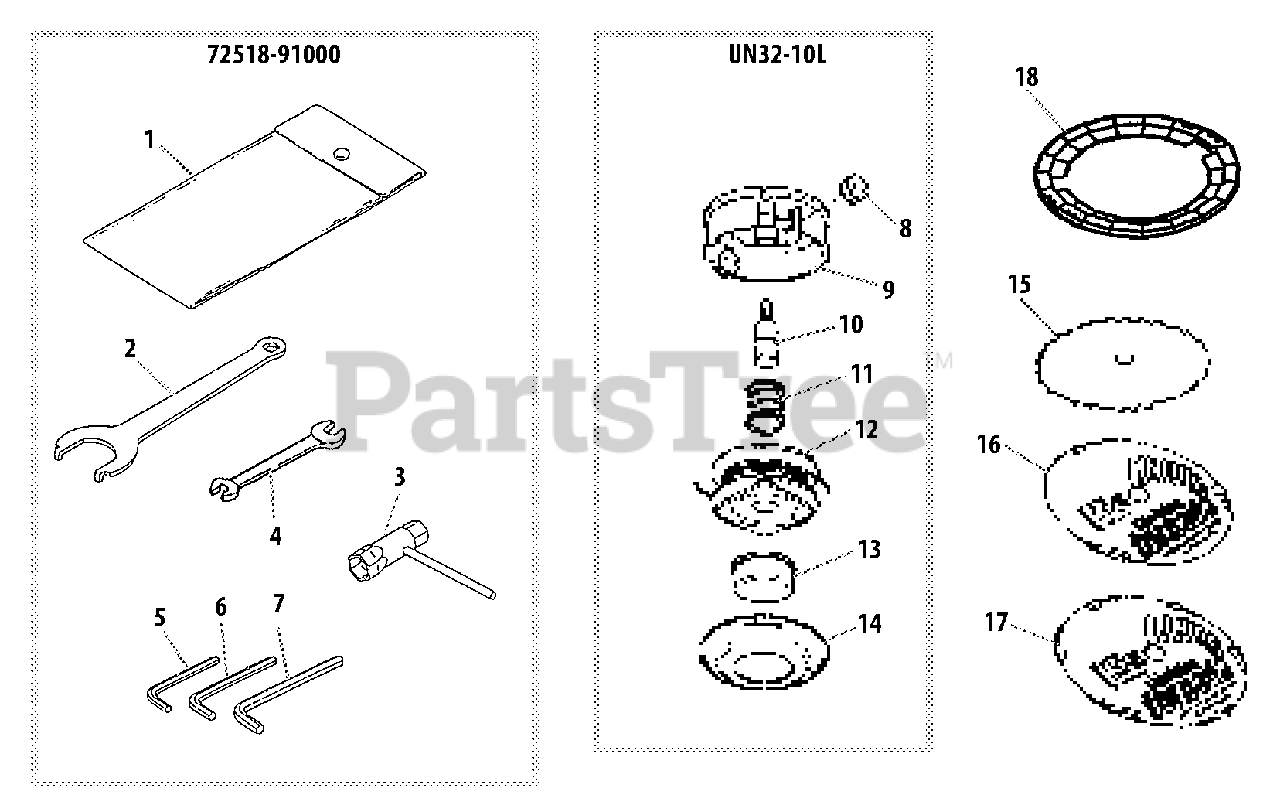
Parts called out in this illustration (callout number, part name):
1	BAG, TOOL
2	SPANNER
3	T-WRENCH 17×19 MM
4	SPANNER 8×10
5	WRENCH, ALLEN 3 MM
6	WRENCH, ALLEN 4 MM
7	WRENCH, ALLEN 5 MM
10	SHAFT BOLT 10 MM LH
15	BLADE - 30 TOOTH -- 9"
16	BLADE - 6 TOOTH -- 9" TORNADO
17	BLADE - 12 TOOTH -- 9" TORNADO
18	COVER, BLADE
72518-91000	SERVICE TOOL KIT
UN32-10L	TRIMMER HEAD ASSY
